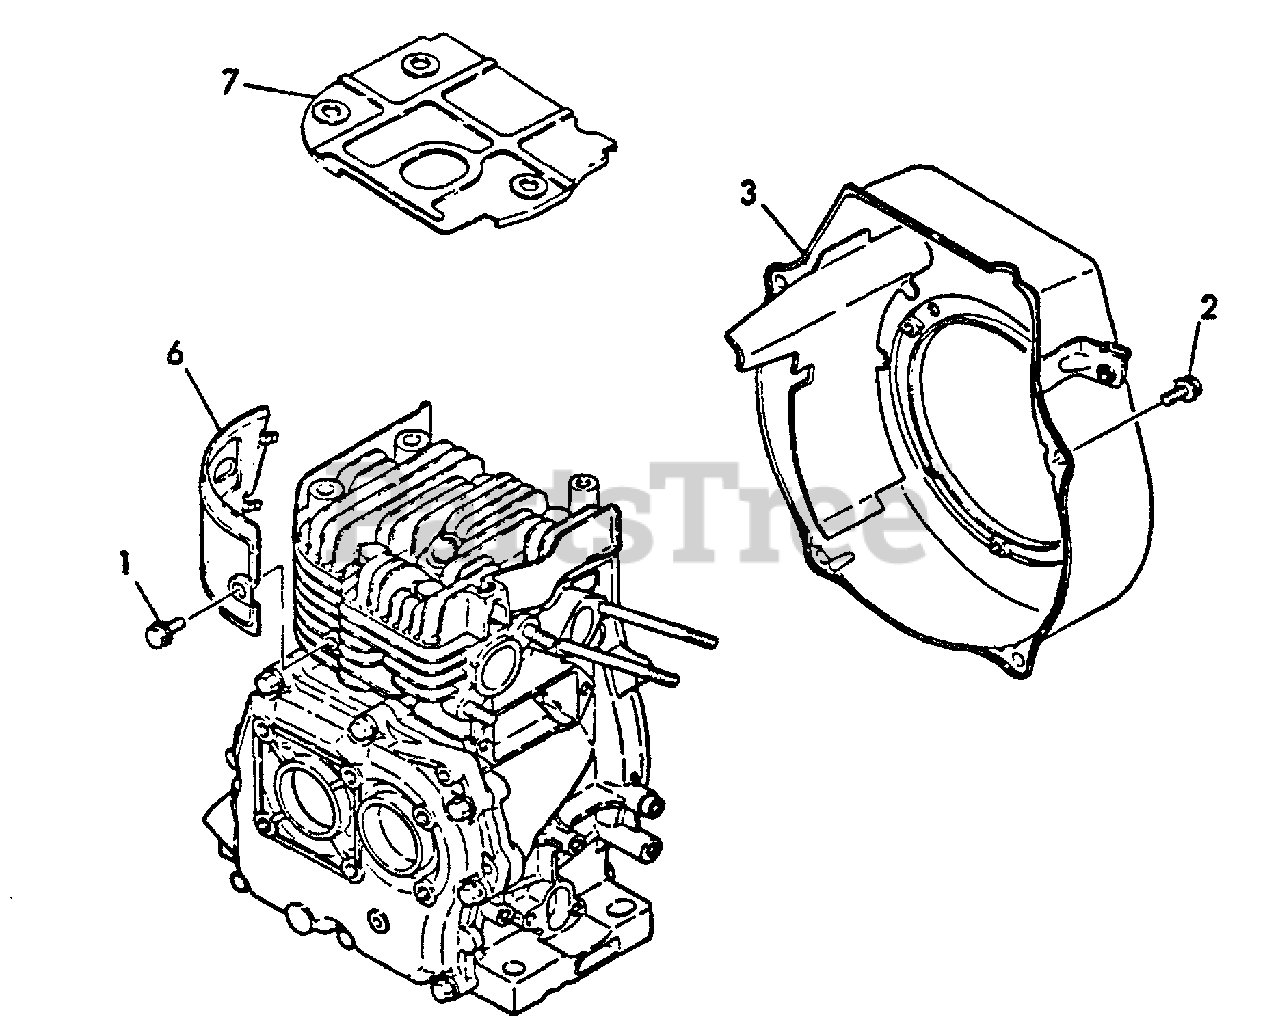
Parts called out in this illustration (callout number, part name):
1	BOLT - 6X8 -- PLATED
2	BOLT - 6X8 -- PLATED
3	COVER, FAN
6	PLATE
7	COVER, HEAD
